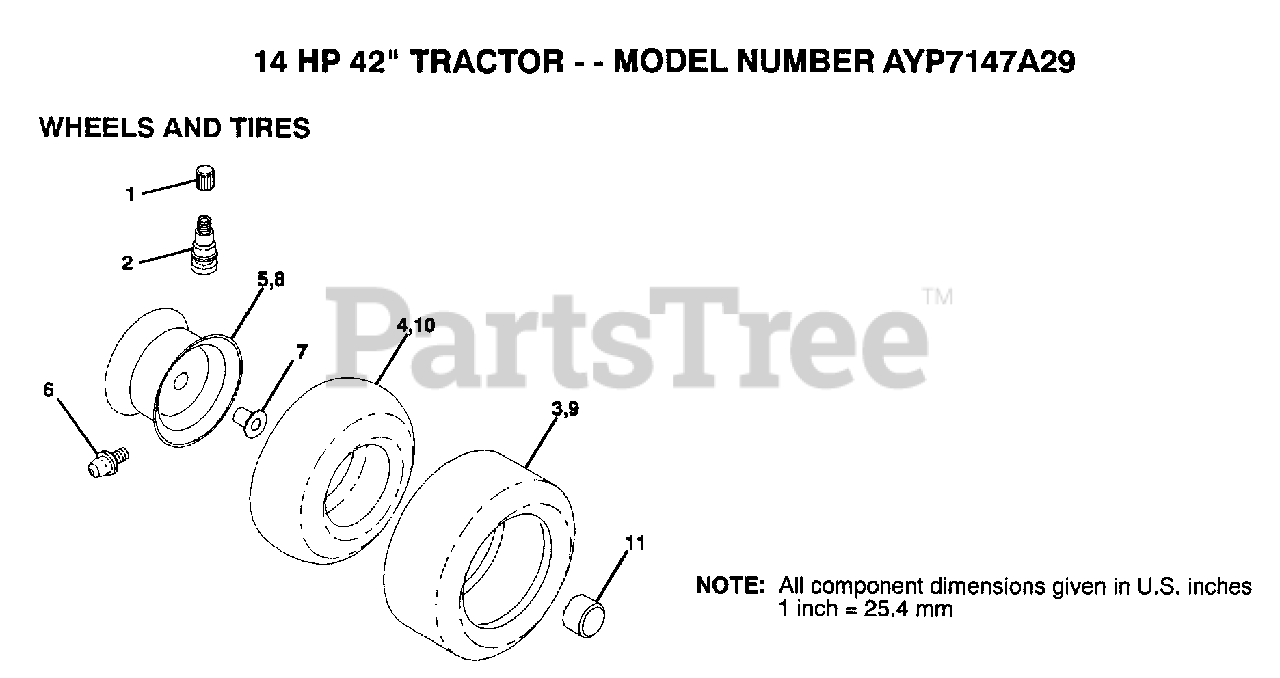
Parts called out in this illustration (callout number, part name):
1	VALVE CAP
2	VALVE STEM LT
4	TUBE.5.3/4.5/6
6	FITTING LT
7	"FLANGE, BEARING"
10	TUBE.18X9.5-8
11	HUB CAP
